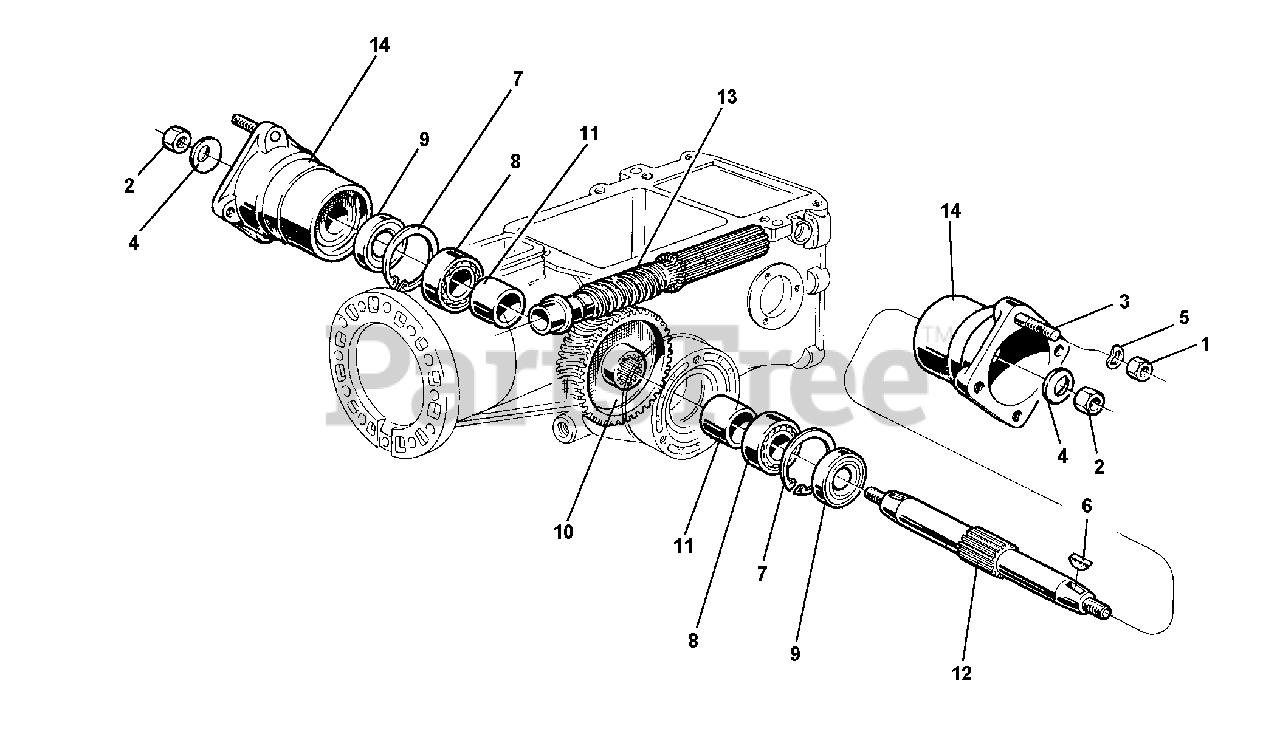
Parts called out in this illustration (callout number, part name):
2	NUT, SELF LOCKING M12
3	STUD M10 X 40 X 22 X 14
4	SUPER WASHER 12 DIN 6796
5	WASHER, LOCK 10.5
6	KEY 6 X 10 UNI 6606
7	CIRCLIP, INTERN D 52
8	BEARING 25 X 52 X 15 6205
9	SEAL, OIL 25 X 52 X 10 STANDARD
10	GEAR Z 49, RH POWER TILLER
12	WHEEL SHAFT
14	HUB, WHEEL, WITH STUDS
